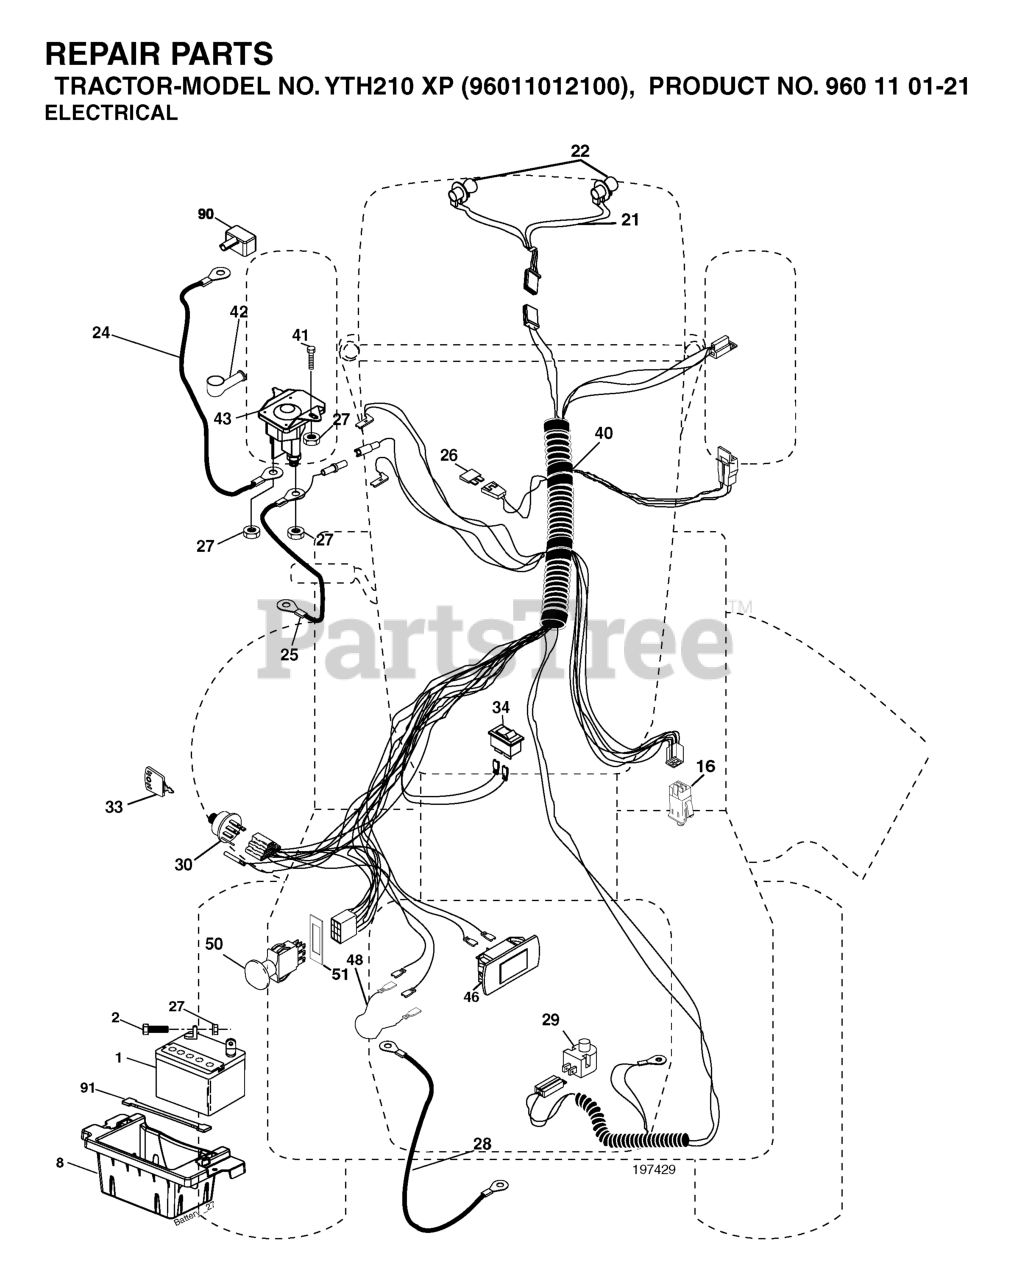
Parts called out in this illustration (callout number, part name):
1	BATTERY 12V .35 AMP
2	BOLT.HEX.1/4.X.3/4.DICHROMATE
8	BOX.BATTERY.MOUNT.FRONT.LT
16	SWITCH INTERLOOK PUSH-IN
21	HARNESS.W/LIGHT SOCKET
24	BATTERY CABLE GT
25	CABLE BATTERY 6 GA 22" W/16W
26	FUSE 20AMP
27	NUT
28	CABLE GROUND 6 GA 21" 90T BLK
29	SWITCH.SEAT.DP W/RAMPS
30	SWITCH.IGN.DELTA.W.LGH.ROS
33	KEY MLD GEN DELTA
40	HARNESS.IGN.ELEC.STL.N/RELY.05
41	BOLT
42	TERMINAL COVER
43	SOLENOID.W/BRASS.PLUNGER
46	GAUGE.SERVICEMINDER.HR
48	ADAPTER.AMMETER
50	RP.PTO.SWITCH.8 TERMINAL.BLACK
51	FRAME RETAINING RING
90	COVER TERMINAL
91	STRAP.BATTERY.MOUNT.FRONT(2 2)
